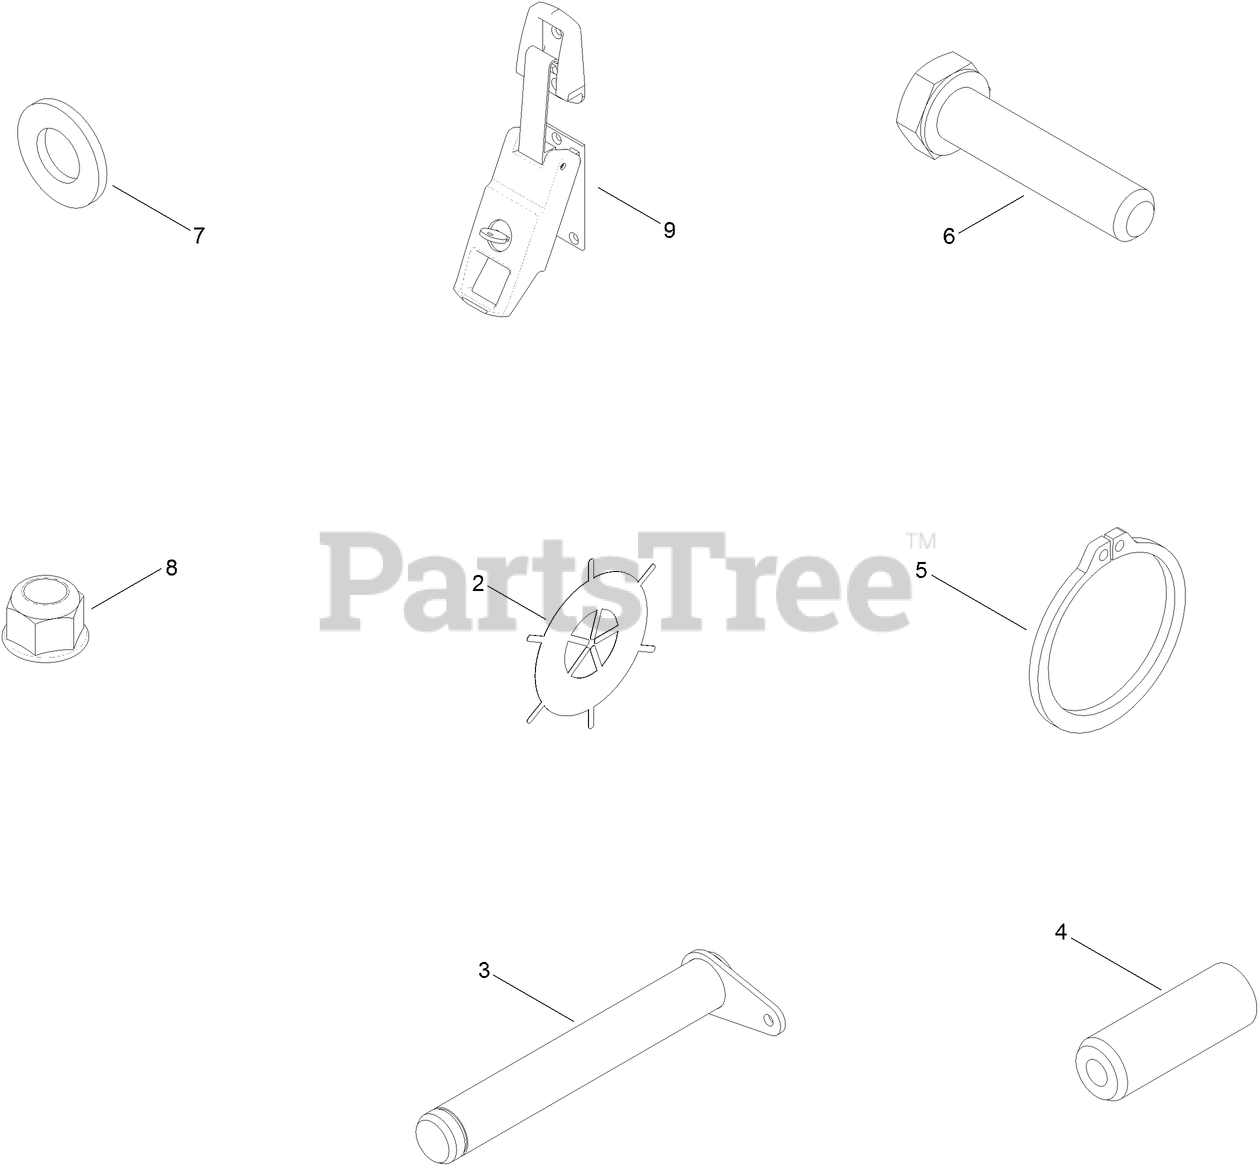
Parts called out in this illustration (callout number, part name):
2	RETAINER-EXHAUST, RING
3	PIN-FLAGGED
4	PIN-TOOL
5	RING-RETAINING, EXTERNAL
6	SCREW-HH
7	WASHER-FLAT
8	NUT-LOCK, NI
9	LATCH-DRAW, LOCKABLE
